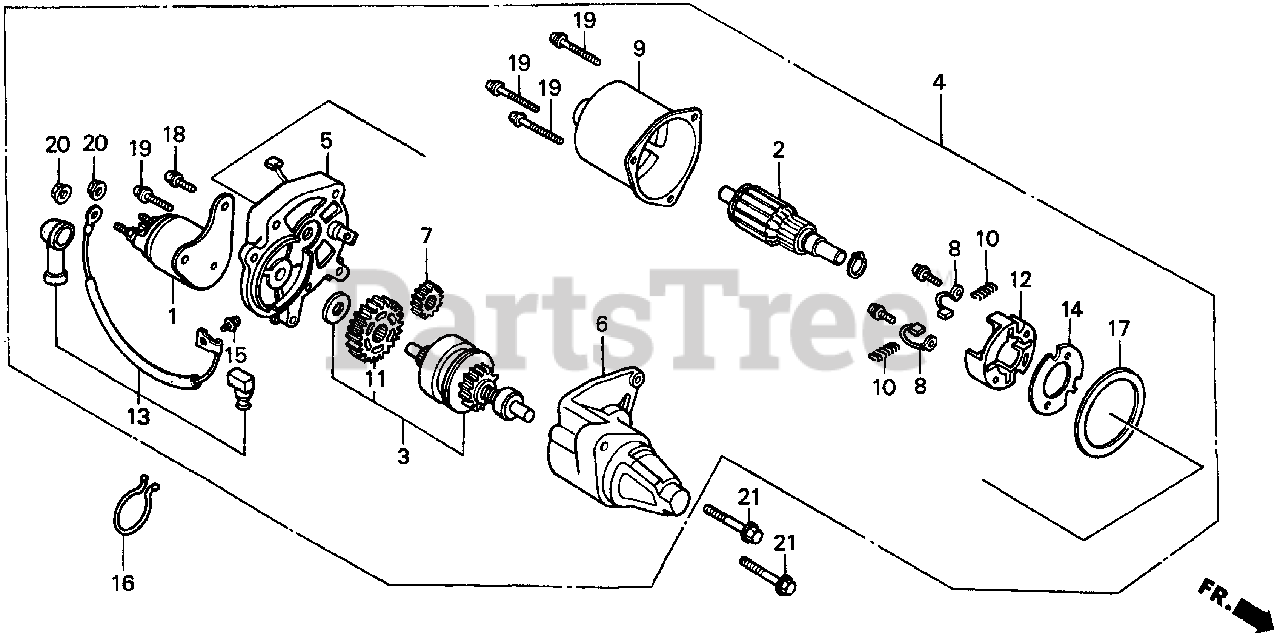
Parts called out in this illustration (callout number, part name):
1	CONTACTOR ASSY.
2	ARMATURE
3	CLUTCH, OVERRUNNING
4	MOTOR UNIT, STARTER
5	BRACKET, CENTER
6	BRACKET, FR.
7	GEAR, DRIVE PINION
8	BRUSH
9	YOKE
10	SPRING, BRUSH RETURN
11	GEAR, REDUCTION
12	HOLDER, BRUSH
13	WIRE, WATER COVER
14	INSULATOR
15	SCREW-WASHER (4X6)
17	GASKET
18	BOLT-WASHER (5X14)
18	SCREW-WASHER (5X14)
19	SCREW-WASHER (5X3)
20	NUT-WASHER (6MM)
21	BOLT, FLANGE (8X35)
